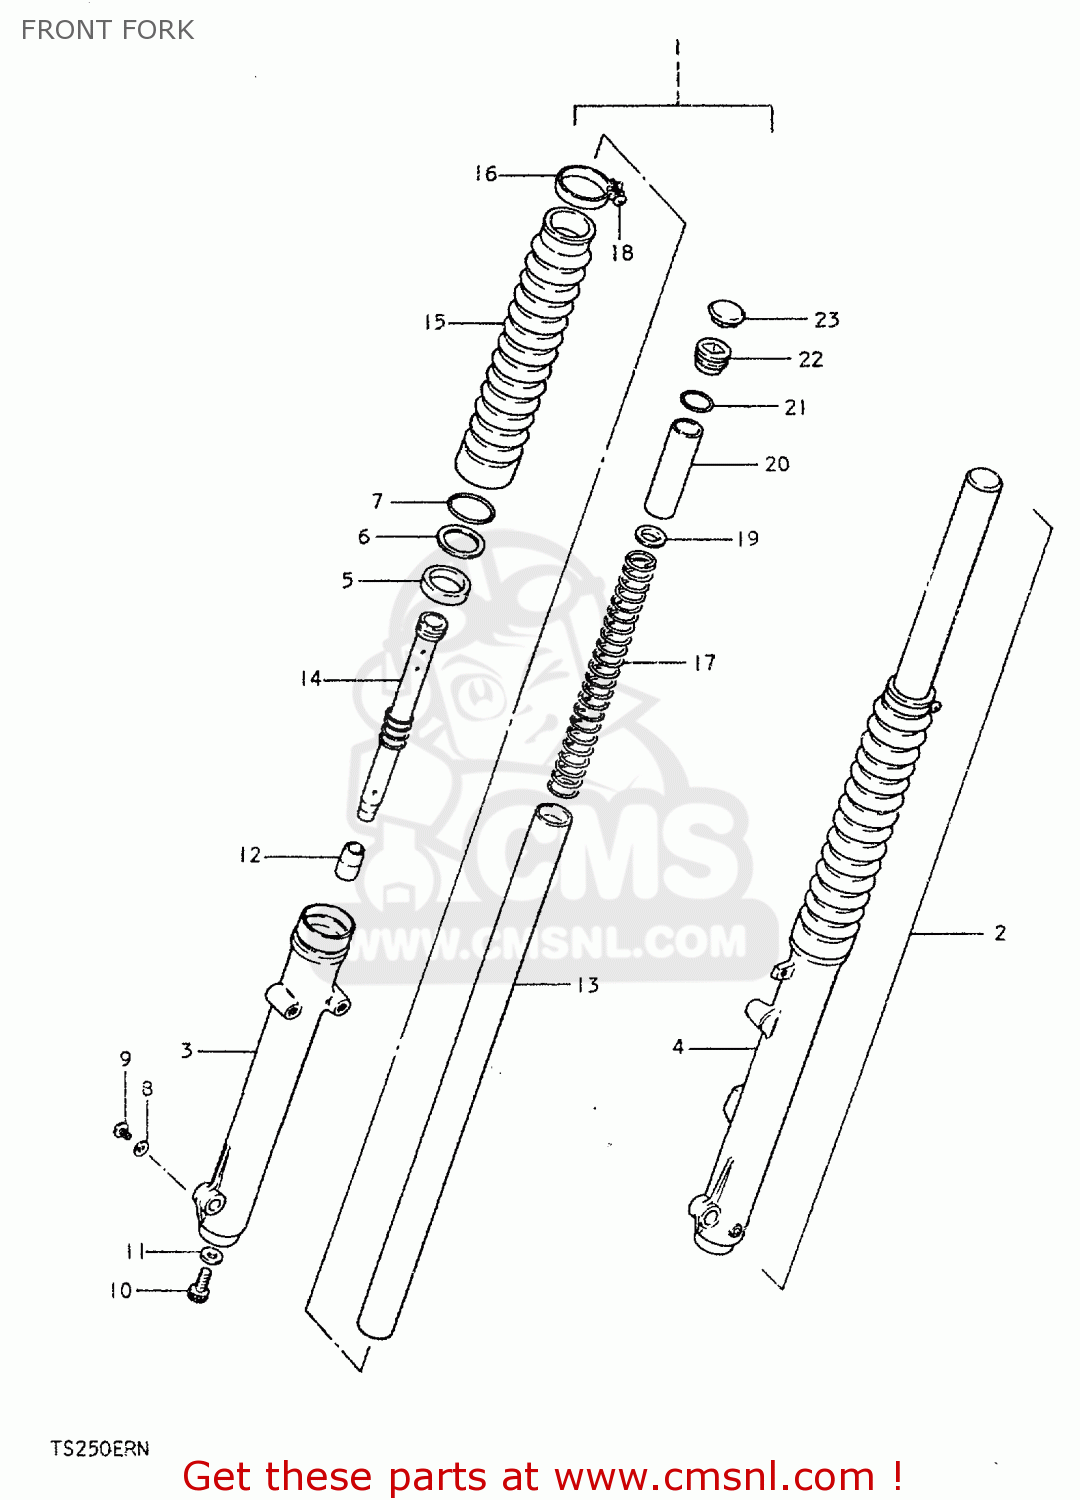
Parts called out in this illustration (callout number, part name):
1	DAMPER ASSEMBLY,FRONT FORK,RIGHT
2	DAMPER ASSEMBLY,LEFT
3	TUBE,OUTER,RIGHT
4	TUBE,FORK,LEFT,OUTER
5	OIL SEAL,FRONT FORK
6	RING,FORK BACK UP
7	CIRCLIP,FORK OIL SEAL
8	GASKET,DRAIN,PLUG (NAS)
9	SCREW
10	BOLT,FORK CYLINDER(10X25)
11	GASKET (NAS)
12	PIECE,OIL LOCK
13	TUBE,FORK,INNER
14	CYLINDER,FRONT FORK
15	BOOT,FRONT FORK COVER
16	BAND,BOOT
17	SPRING,FRONT FORK
18	SCREW
19	GUIDE,FRONT FORK SPRING C
20	SPACER,FRONT FORK SPRING
21	O RING
22	CAP,FORK INNER TUBE
23	CAP,FRONT FORK
